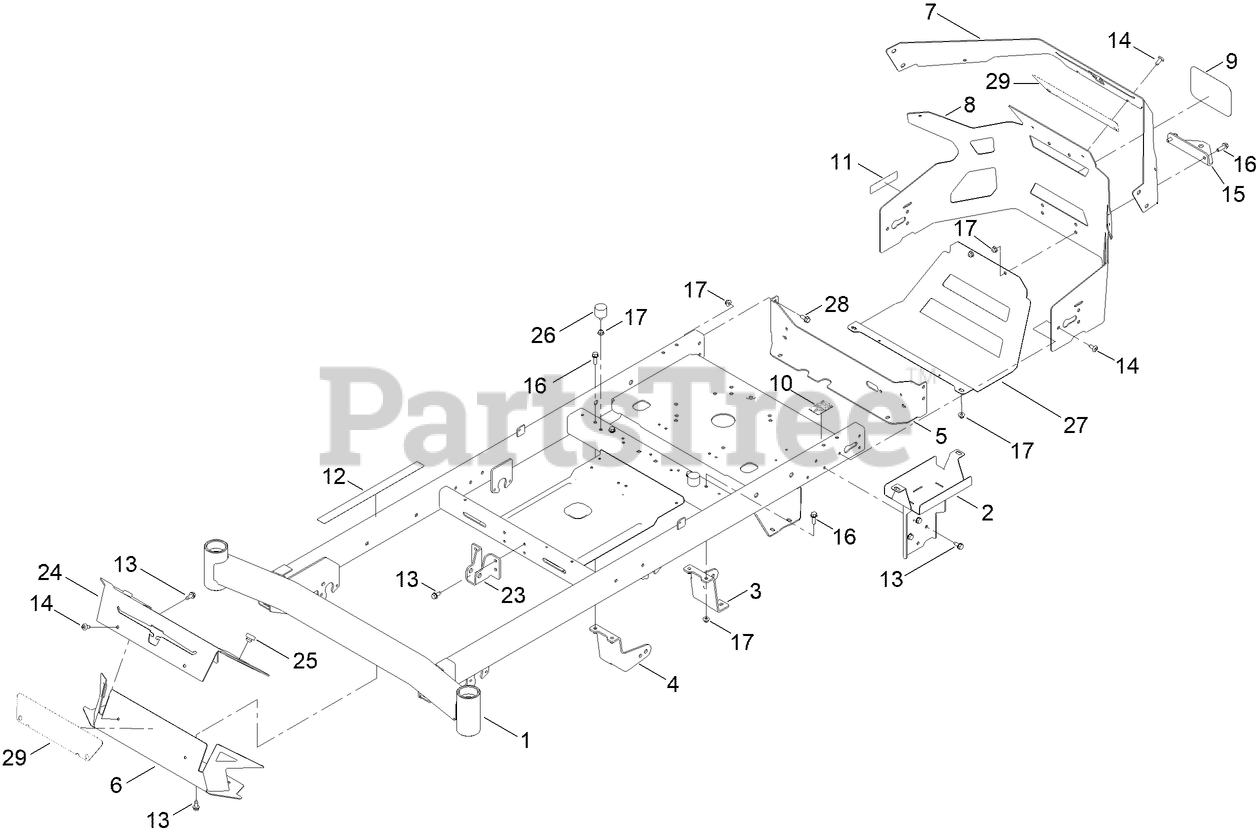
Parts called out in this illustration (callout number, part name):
1	SERVICE ASM-FRAME, TC
2	WA-BATTERY MOUNT
3	MOUNT-DRIVE, LH
4	MOUNT-DRIVE, RH
5	PLATE-MOUNT
6	FOOTREST-TOP
7	PLATE-REAR CLADDING TC
8	GUARD-ENGINE TC
10	DECAL-BYPASS
11	DECAL-SPARK ARRESTER
12	DECAL-WARNING
13	SCREW-HWHTF
15	BRACKET-HITCH
16	SCREW-HHF
17	NUT-HF
23	BRACKET-MOUNT DAMPER, LOWER
24	PLATE-KICK, MR
25	BUMPER-RUBBER
26	BUMPER-RUBBER
27	GUARD-MUFFLER [BLACK]
28	SCREW-HHF
29	DECAL-BACKER, RED
